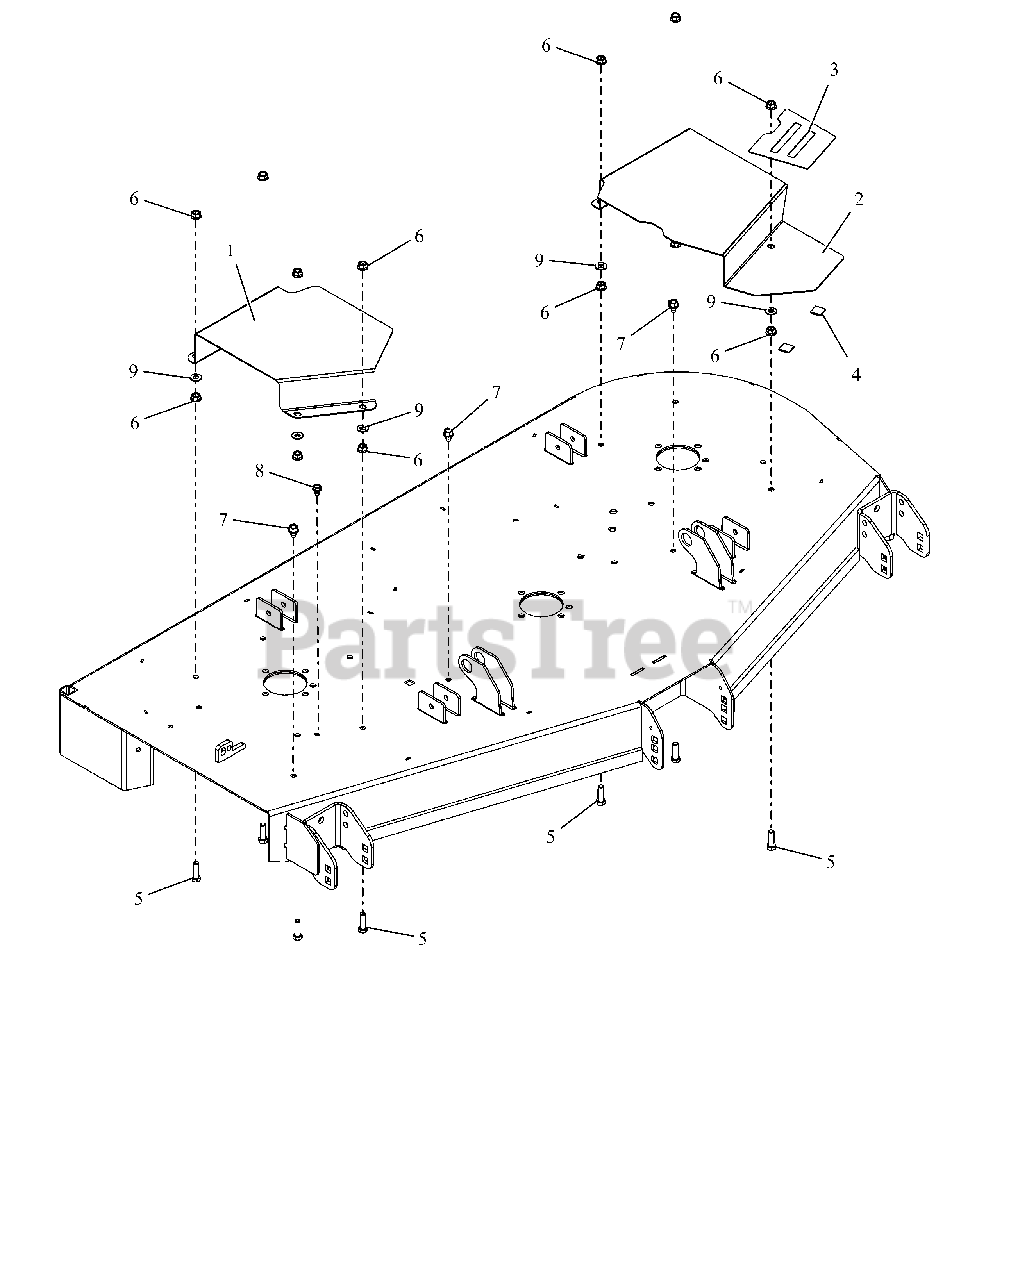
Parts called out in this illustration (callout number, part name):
1	COVER, BELT 52" & 60" RIGHT
2	COVER, BELT 60" LEFT
3	GRIP, TAPE 52-60 BELT COVER
5	@BLT-HEX .38-16X1.25 GR5 YWZC
6	@NUT-SPNLK-FLG .375-16 YWZC
7	@SCR-TAP .38-16X.50 HWH TR YWZ
8	@SCR-TAP .31-18X.50 HWH TR YWZ
9	@WSHR-FL-STL.406X.812X.065 YWZ
